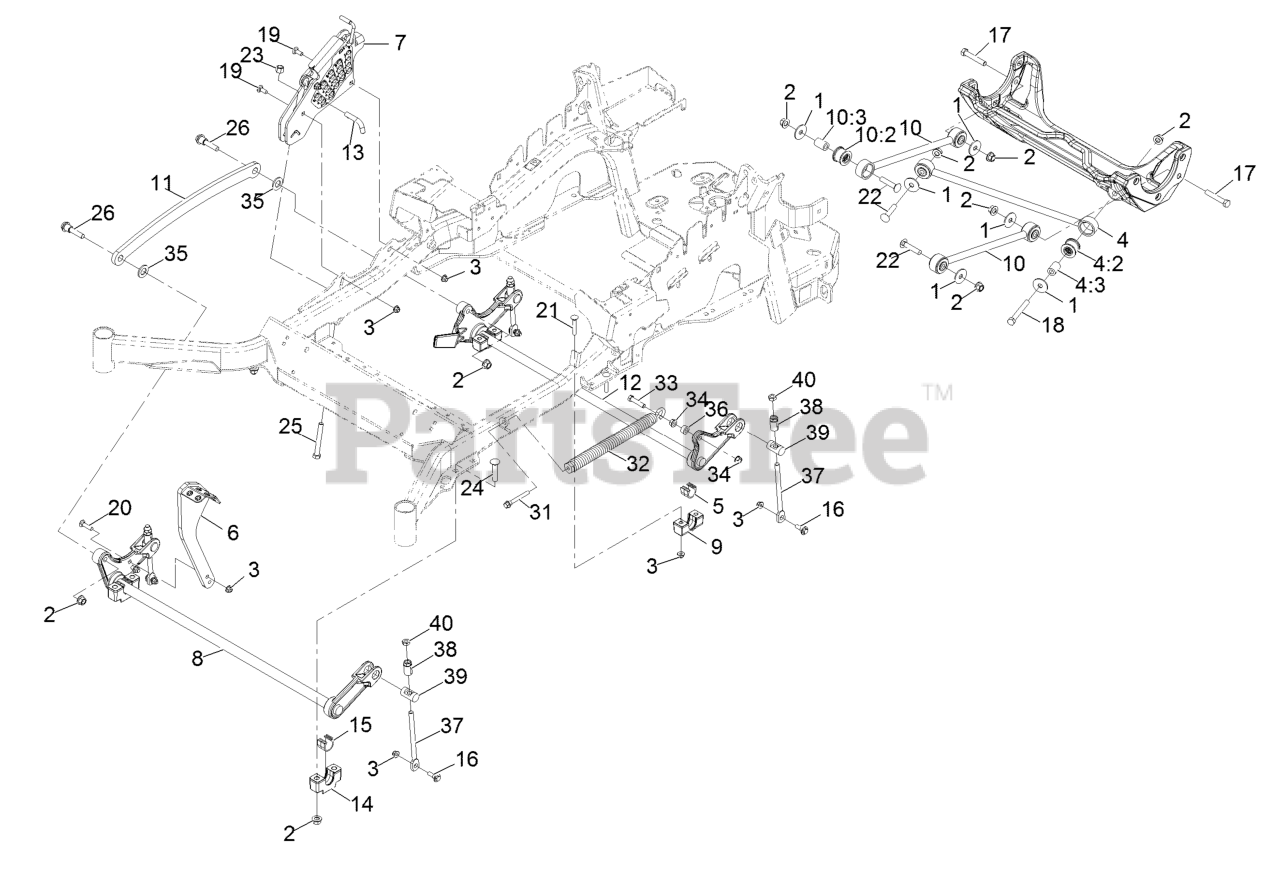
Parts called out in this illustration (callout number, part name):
1	WASHER-THRUST
2	Nut-Lock 1/2-13
3	NUT-HF, NI
4	PANHARD ROD ASM
4:2	BUSHING-SUSPENSION, RUBBER
5	BEARING-CROSS SHAFT, REAR
6	LEVER-FOOT
7	HOC ASM
8	DECKLIFT-FRONT
9	SUPPORT-CROSS SHAFT, BEARING REAR
10	DECK STRUT ASM
10:2	BUSHING-SUSPENSION, RUBBER
11	LINK-LIFT, DECK
12	LIFT-DECK, REAR
13	PIN-HOC
14	SUPPORT-CROSS SHAFT, BEARING
15	BEARING-CROSS SHAFT, FRON
16	SCREW-SHOULDER, HHF
17	SCREW-HH
18	SCREW-HH
19	BOLT-CARR
20	SCREW-CARR
21	Bolt-Carriage 3/8-16 X 2 1/4
22	SCREW-CARR
23	NUT-LOCK, NI
24	Bolt-Carriage 1/2-13 X 2 1/2 Spl Neck
25	BOLT-TAP
26	SCREW-HHF, SHOULDER
31	BOLT-SHOULDER
32	SPRING-EXTENSION
33	SCREW-HH
35	WASHER-FLAT
37	LINK-ADJUSTER, DECK LIFT
38	ADJUSTER-LIFT, DECK
39	TRUNNION
40	NUT-JAM
